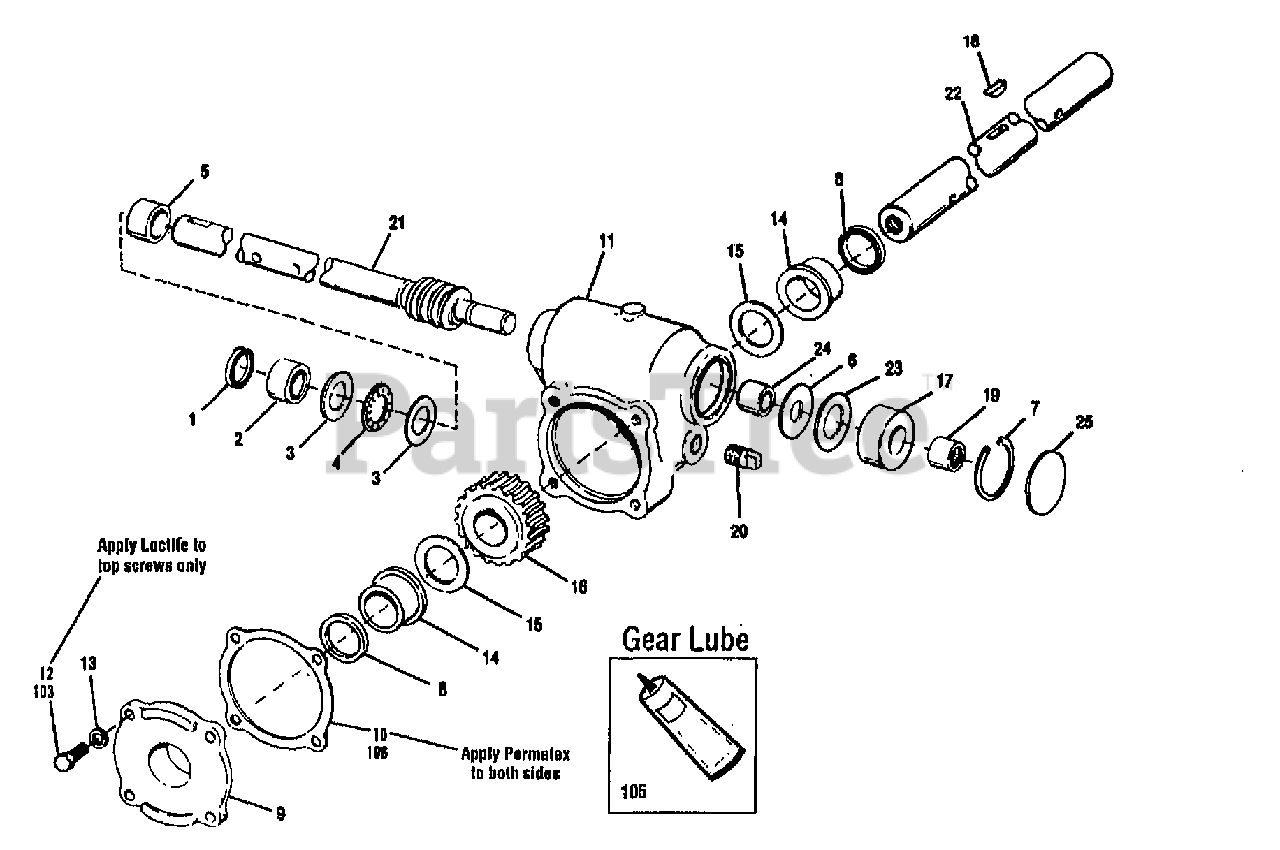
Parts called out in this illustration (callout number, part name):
1	SEAL-OIL 3/4 DIAMETER
2	BEARING-NEEDLE
3	RACE-THRUST
4	BEARING-THRUST
5	SPACER-1.0X.752X.302
6	WASHER
7	RING-RETAINING INTERNAL
8	SEAL-OIL
9	COVER-FLANGED
10	GASKET-COVER
11	CASE ONLY-GEAR
12	SCR-HH 1/4-20X.625 G5 ZP
13	WASHER-LK .25 ZP
14	BUSHING-FLANGE
15	RACE-THRUST
16	GEAR-WORM 20 TEETH
17	SPACER-1.503X.749X.56
18	KEY-WOODRUFF .25X.875
19	BEARING-NEEDLE
20	PLUG-SQ HEAD 1/4-18 NPT
21	ASSM-SHAFT IMPELLER 21"
22	SHAFT-AUGER
23	RACE-THRUST
24	SPACER-.812X.566X.448
25	PLUG-EXPANSION
103	LOCTITE-242 (.5 ML TUBE)
105	LUBE-EP90 8OZ
106	GASKET COMPOUND
